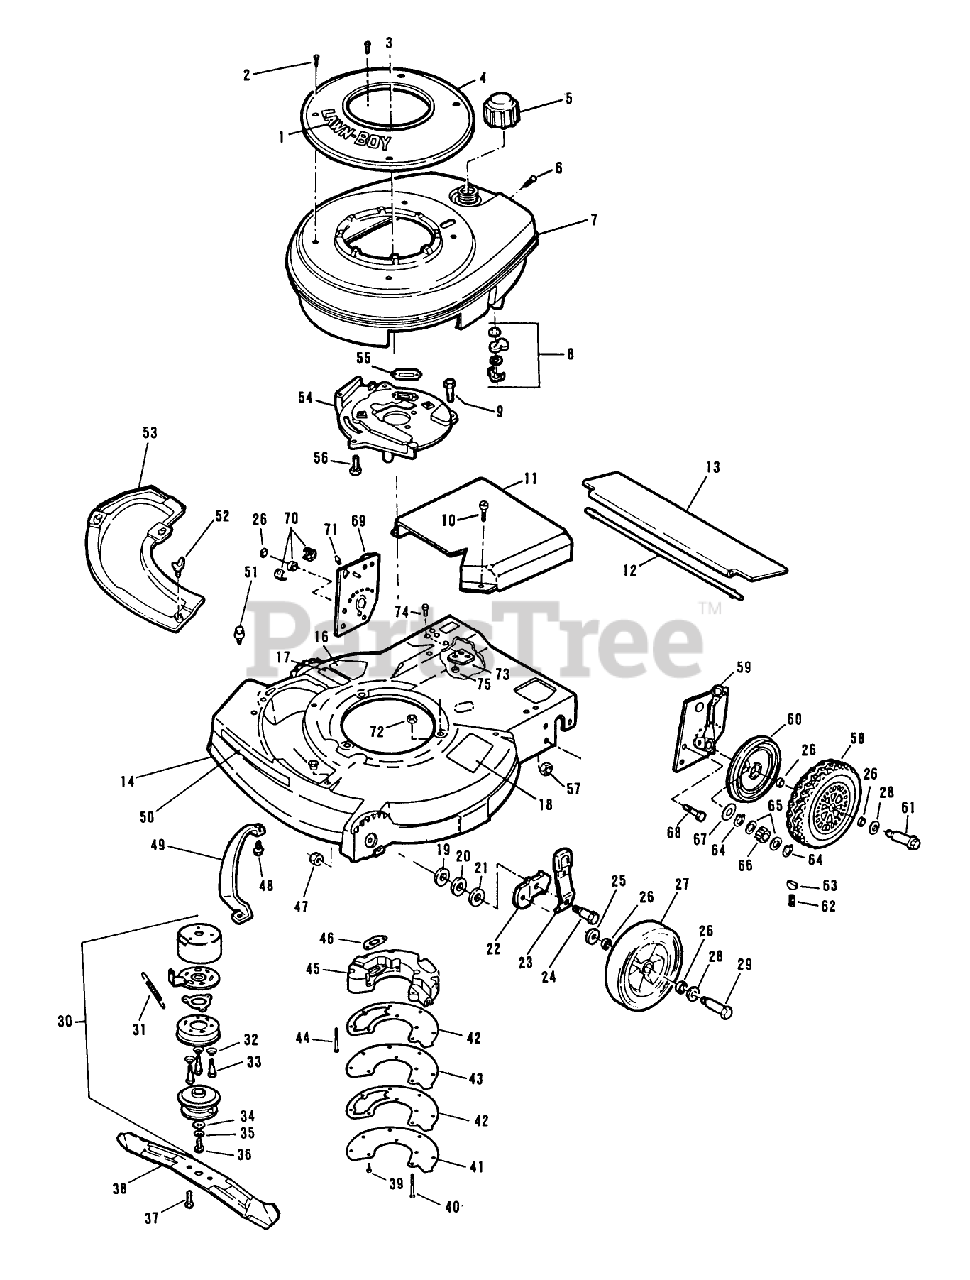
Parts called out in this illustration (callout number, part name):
2	SCREW - SELF TAPPING
3	SCREW SEMS SM
5	FUEL CAP & INSERT
6	SCREW S
8	SHUT OFF VALVE KIT
9	SCREW-HH
10	SCREW SEMS TRM HEX HD
18	PAD FOOT
19	WASHER
20	WASHER
21	WASHER
23	SPRING ARM ASM
24	BOLT
25	WASHER WROUGHT
26	WASHER
28	SPACER
29	BOLT WHEEL
31	SPRING
33	SCREW,SHOULDER SM
34	WASHER
37	SCREW SEMS
38	21" Blade
39	SCREW
42	GASKET F
47	LOCKNUT
49	BAR-TOE
52	WING SCREW LAWRE
56	SCREW V
57	NUT-LOCK F
61	BOLT WHEEL
62	SPRING
63	KEY
64	RET RING
65	SPACER/GR ALGHNY
66	PINION BROCKWAY
70	REAR AXLE BEARING
71	**FITTING LINCOLN
72	NUT-LOCK F
73	BOLSTER
75	LOCKNUT E
